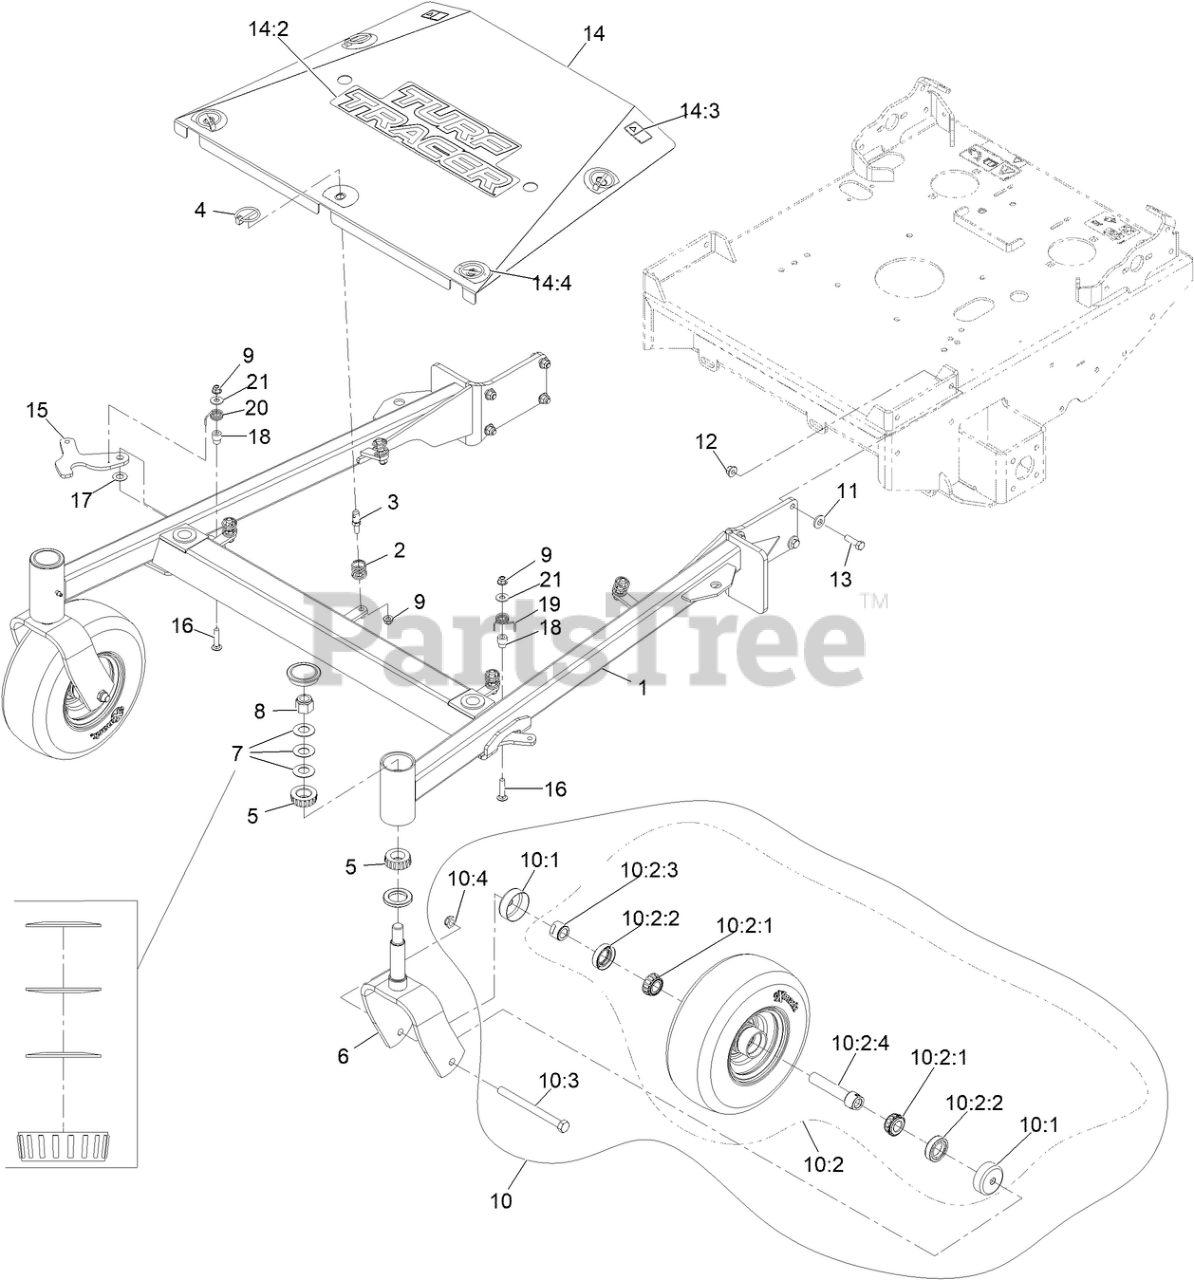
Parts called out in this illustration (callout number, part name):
1	ASM, FRONT FRAME W/ BEARINGS, 52
3	PIN, SPRING
4	PIN-LYNCH
5	Cone-Bearing Tapered Roller
6	WLD, CASTER FORK
7	WASHER-BELLVILLE
8	NUT-LOCK, NI
9	NUT-HF, NI
10	ASM,WHEEL&BEARINGS
10:1	GUARD-SEAL
10:2	Wheel And Bearing ASM
10:2:1	BEARING-CONE, TAPERED ROLLER
10:2:2	SEAL-CASTER
10:2:3	SPACER-NUT
10:2:4	CASTER AXLE ASM
10:3	SCREW-HH
10:4	NUT-HEX
11	WASHER-BELLEVILLE
12	NUT-HF, NI
13	SCREW-HH
14	ASM, CENTER SHIELD W/ DECALS, 52
14:2	DECAL-TURF TRACER
14:3	DECAL-WARNING
14:4	DECAL-SCRATCH COVER
15	LATCH, DECK HEIGHT
16	BOLT-CARR
17	Washer-Plastic
18	COLLAR-BASKET
19	SPRING-TORSION, LH (YELLOW)
20	Spring-Torsion, RH
21	WASHER-FLAT
